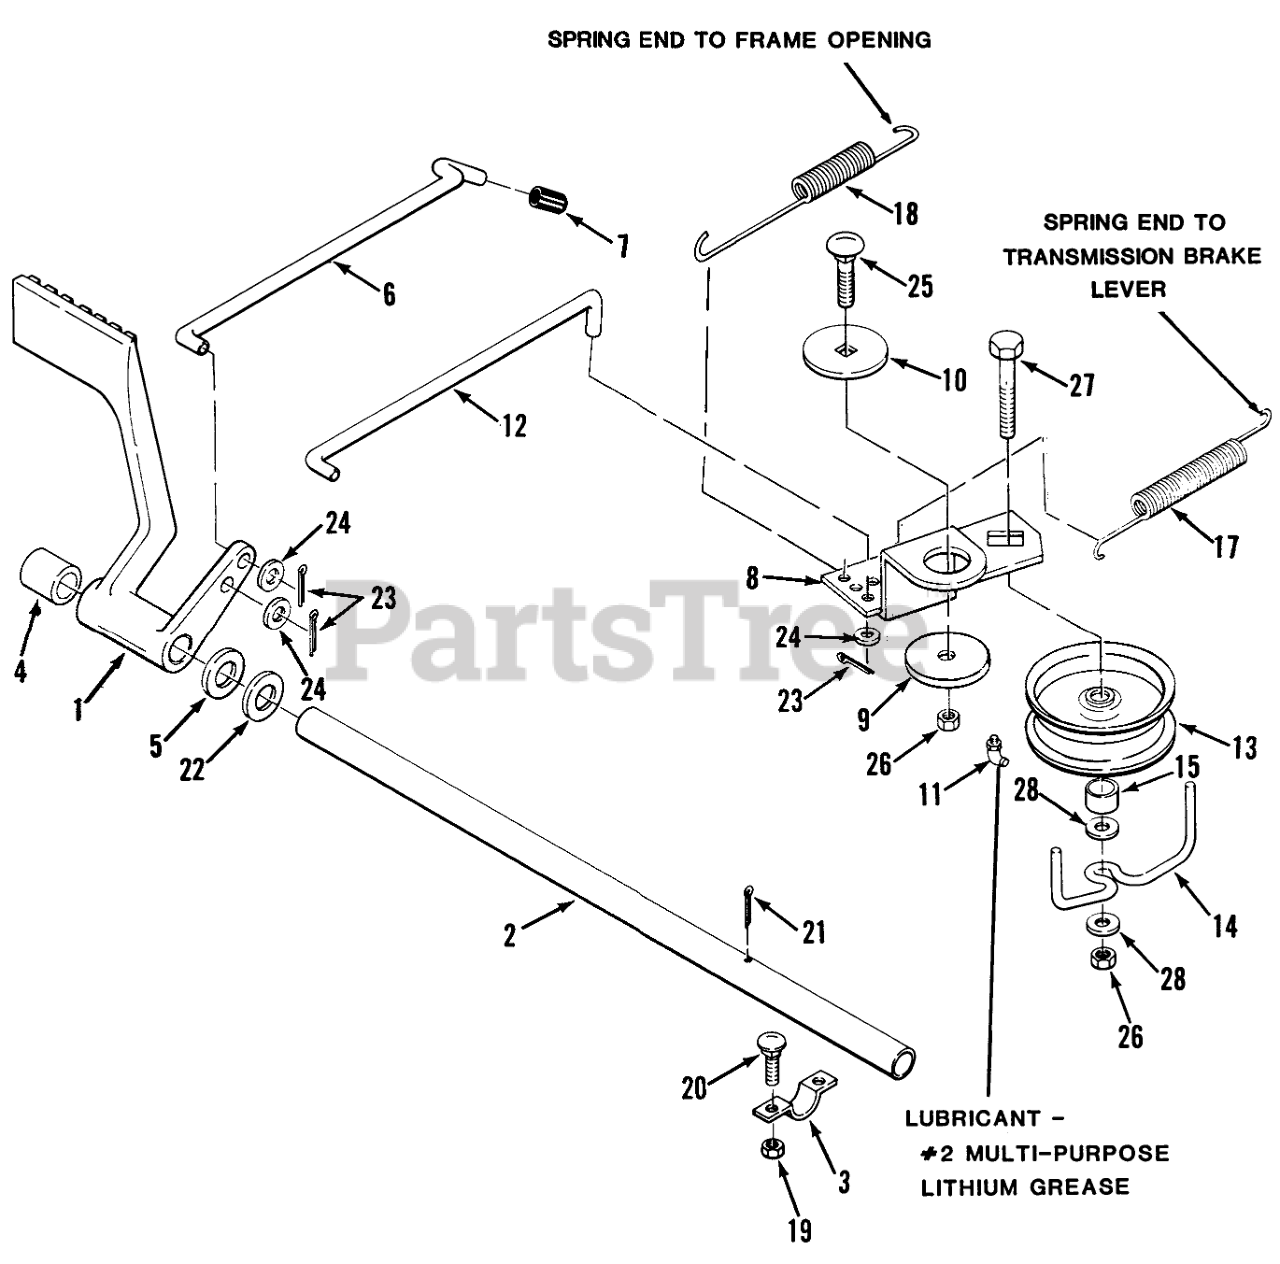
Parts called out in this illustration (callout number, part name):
1	PEDAL BRAKE R
2	SHAFT PEDAL
3	CLAMP
4	SPACER
5	WASHER-WAVE
6	Lock Rod
8	ARM-IDLER R
9	BUSHING
10	WASHER-BEARING
11	Fitting-Grease
12	ROD CLUTCH BRAKE
13	PULLEY IDLER
14	GUIDE-BELT
15	SPACER
17	SPRING - BRAKE
18	SPRING - CLUTCH
19	Nut
20	Bolt
22	Washer
23	Cotter Pin
24	WASHER 5/16 SAE
25	Bolt
26	NUT
27	Carriage Bolt 3/8-16 x 2-1/4
28	Washer
